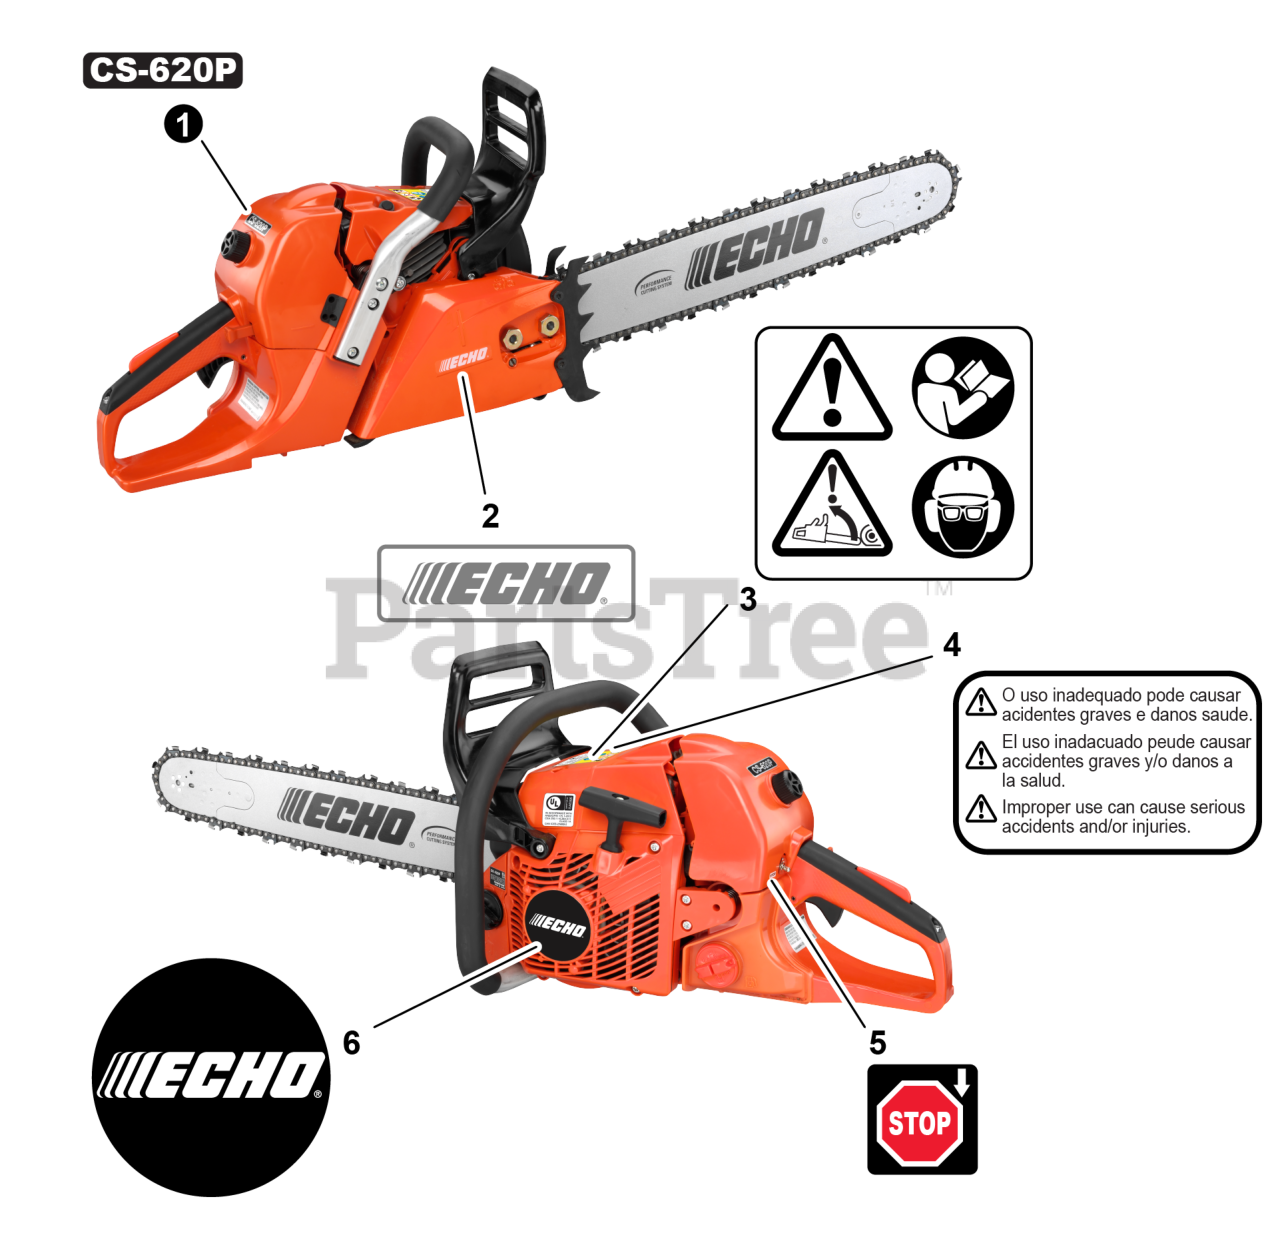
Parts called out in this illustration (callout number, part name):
1	LABEL - MODEL CS-620P
2	LABEL - ECHO
3	LABEL - CAUTION
4	LABEL - CAUTION
5	LABEL - STOP
6	LABEL - RECOIL STARTER
